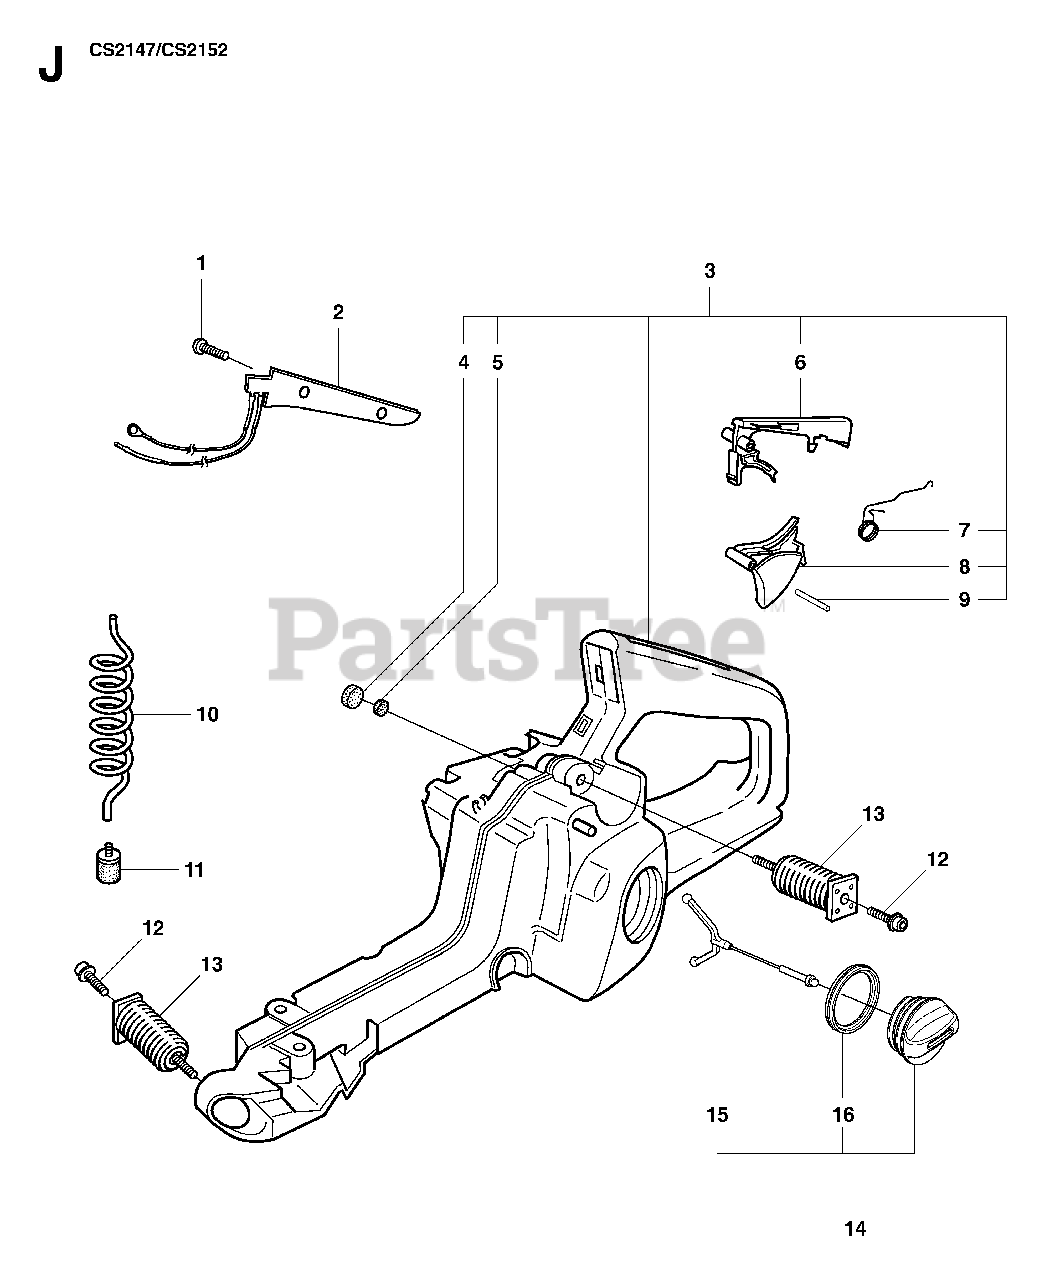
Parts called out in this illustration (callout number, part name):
2	PLATE (G)
3	TANK UNIT
4	FILTER PLUG
5	VALVE PLUG
6	THROTTLE LOCK
8	THROTTLE TRIGGER
10	FUEL HOSE
11	FUEL FILTER
13	VIBRATION ABSORBER
14	TANK CAP
16	SEALING
